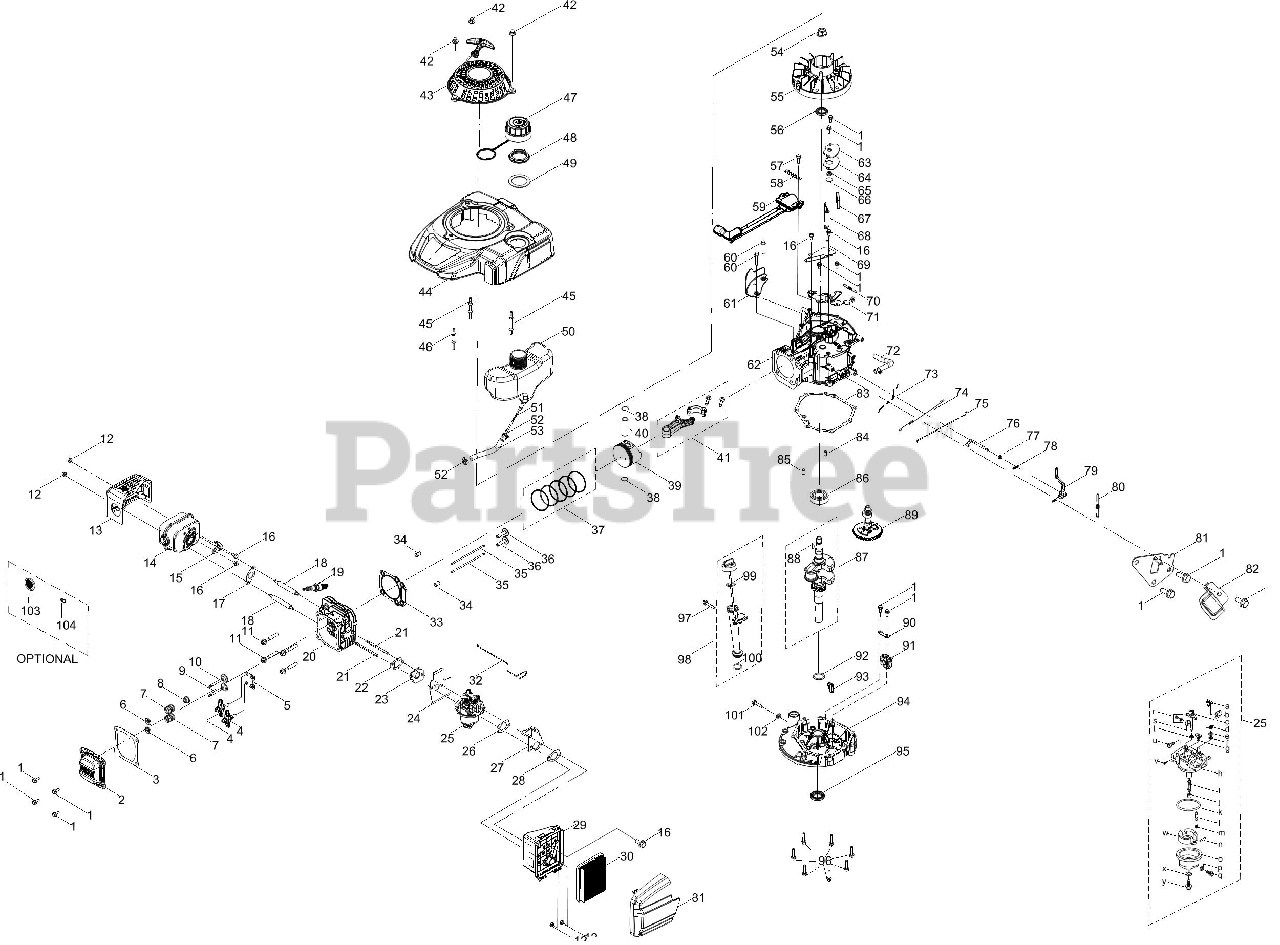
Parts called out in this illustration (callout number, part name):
1	Bolt M6x14
2	Valve Cover
3	Valve Cover Gasket
4	Rocker Arm Assembly
5	Push Rod Guide
6	Valve Spring Retainer
7	Valve Spring
8	Intake Valve Seal
9	Exhaust Valve
10	Intake Valve
11	Bolt M8x54
13	Muffler Shield
14	Muffler Assembly
15	Choke Thermal Control
16	Bolt M6x12
17	Muffler Gasket
18	Muffler Stud M6x95
19	Spark Plug/F5RTC
20	Cylinder Head
21	Carb Stud M6x87
22	Carburetor Insulator Gasket
23	Carburetor Insulator
24	Carburetor Gasket
25	Carburetor Assembly
26	Air Filter Bracket Gasket
27	Air Filter Bracket
28	Air Filter Base Gasket
29	Air Filter Base
30	Air Filter Element, Paper
31	Air Filter Cover
32	Temp Control Linkage
33	Cylinder Head Gasket
34	Cylinder Head Dowel Pin 10x16
36	Tappet
37	Piston Ring Set
38	Piston Pin Snap Ring
39	Piston
40	Piston Pin
41	Connecting Rod Assembly
42	Starter Acorn Nut
43	Starter Recoil Assembly
44	Engine Shroud Assembly
45	Shroud Stud M6x78.5
46	Shroud Stud M6x74
47	Fuel Cap Assembly
48	Fuel Tank Nut
49	Fuel Tank Upper Grommet
50	Fuel Tank
51	Fuel Filter
52	Fuel Hose Clamp
53	Fuel Hose
54	Flywheel Nut M14
55	Flywheel
56	Upper Crankshaft Seal
57	Bolt M6x20
58	Flexible Clamp
59	Ignition Coil Assembly
60	Bolt M6x25
61	Engine Brake Cover Plate
63	Breather Cover Plate
64	Breather Gasket
65	Breather Valve Spring
66	Breather Valve
67	Breather Screen
68	Air Vane
69	Air Vane Bracket
70	Brake Spring
71	Brake Assembly
72	Breather Hose Assembly
73	Choke Linkage
74	Throttle Linkage
75	Throttle Linkage Spring
76	Governor Arm Shaft
77	Governor Seal
78	Governor Arm Shaft Cotter Pin
79	Governor Arm Assembly
80	Governor Spring
81	Component Bracket
82	Governor Shield
83	Crankcase Cover Gasket
84	Crankcase Cover Dowel Pin 7x14
85	Crankcase Cover Dowel Pin 9x14
86	Main Bearing
87	Crankshaft Assembly
88	Flywheel Key
89	Camshaft Assembly
90	Governor Gear Mounting Plate
91	Governor Gear/Shaft Assembly
92	Crankshaft Thrust Washer
93	Oil Return Seal
94	Crankcase Cover
95	Lower Crankshaft Seal
96	Bolt M6x28
97	Bolt M6x35
98	Dipstick Assembly
99	Dipstick / Oil Fill Tube O-Ring
100	Dipstick / Oil Fill Tube O-Ring
101	Oil Drain Plug
102	Oil Drain Plug Washer
103	Spark Arrestor
104	Spark Arrestor Screw
